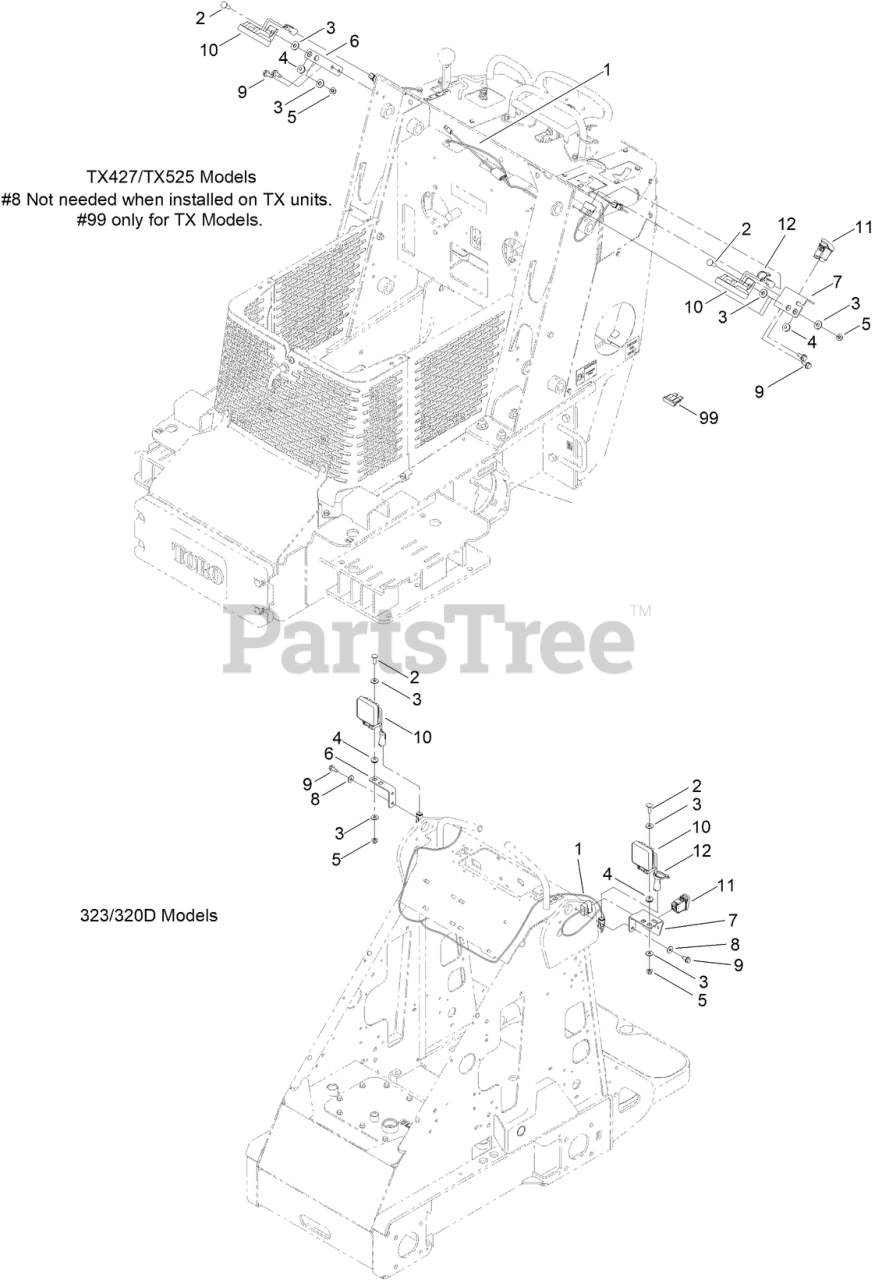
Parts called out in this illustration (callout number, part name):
1	HARNESS-WIRE,WORK LIGHT
2	SCREW-CARR
3	WASHER-FLAT
4	GROMMET-RUBBER
5	NUT-HF, NI
6	BRACKET-LIGHT
7	BRACKET, LIGHT SWITCH
8	WASHER-BELLEVILLE
9	SCREW-HWHTF
10	LIGHT-WORK, LED
11	SWITCH
12	TIE-CABLE
99	FUSE-BLADE, 10 AMP
